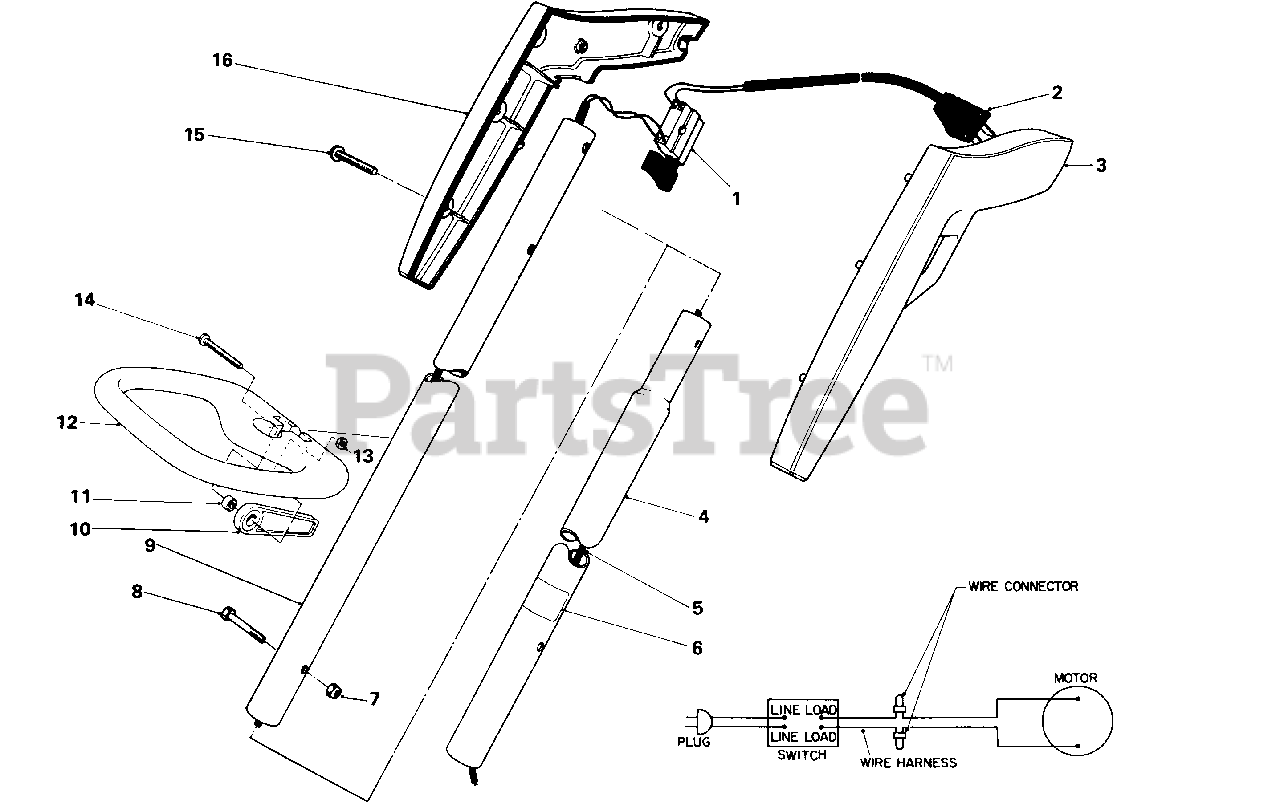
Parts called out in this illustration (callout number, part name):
1	Switch-Single Speed
2	Plug-Pig Tail
3	Grip, L.H.
4	Tubing-Lower Extension
5	Wire Harness
6	Decal-Serial
8	Hex. Hd. Machine Screw
9	Tubing-Upper Extension
10	Cam Adjustment Knob
11	Spacer-Adjustment Knob
12	Handle-Adjustable
13	Hex. Nut
14	Slotted Hd. Pan Screw
15	Cross Recess Pan Head Thread Forming Screw
16	Grip, R.H.
